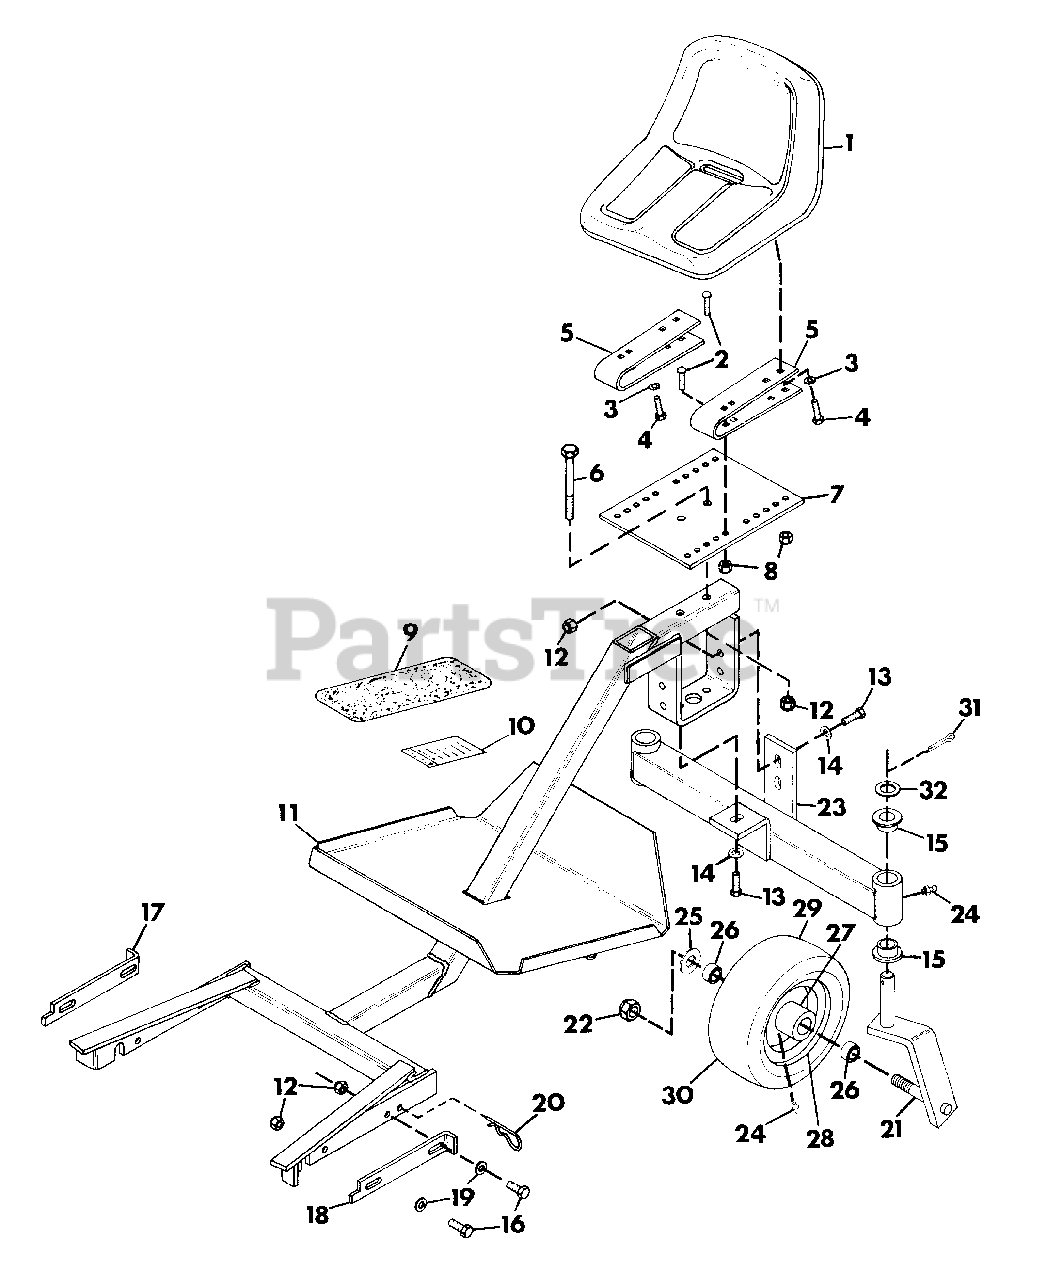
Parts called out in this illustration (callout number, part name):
1	SEAT, HIGH BACK
2	BOLT, 5/16-18X.875 RD HD SQ NK
3	WASHER, LOCK 5/16 REG.
4	BOLT, HEX 5/16-18X.75
5	SPRING, SEAT
6	BOLT, HEX 3/8-16X2.75
7	PLATE, SEAT SUPPORT
8	NUT, LOCK 5/16-18
9	COVER, LARGE FOOTBOARD
10	DECAL, SULKY PRO 40/PRO 50
11	WELDMENT, FRAME
12	NUT, LOCK 3/8-16
13	BOLT, HEX 3/8-16X1.25
14	WASHER, FLAT .406X.812X.065
15	BUSHING, PIVOT
16	BOLT, HEX 3/8-16X1.125
17	STRAP, SULKY LATCH R.H.
18	STRAP, SULKY LATCH L.H.
19	WASHER, FLAT .375X1.125X.065
20	PIN, HAIR
21	WELDMENT, CASTER FORK
22	NUT, LOCK 3/4-10
23	WELDMENT, AXLE
24	FITTING, LUBE 1/4-28
25	WASHER, FLAT .812X1.496X.134
26	BEARING
27	WHEEL
28	TUBE
29	TIRE
30	ASSEMBLY, WHEEL AND TIRE
31	PIN, COTTER .187X1.62
32	RACE, BEARING THRUST
NS	DECAL, AMERICA
